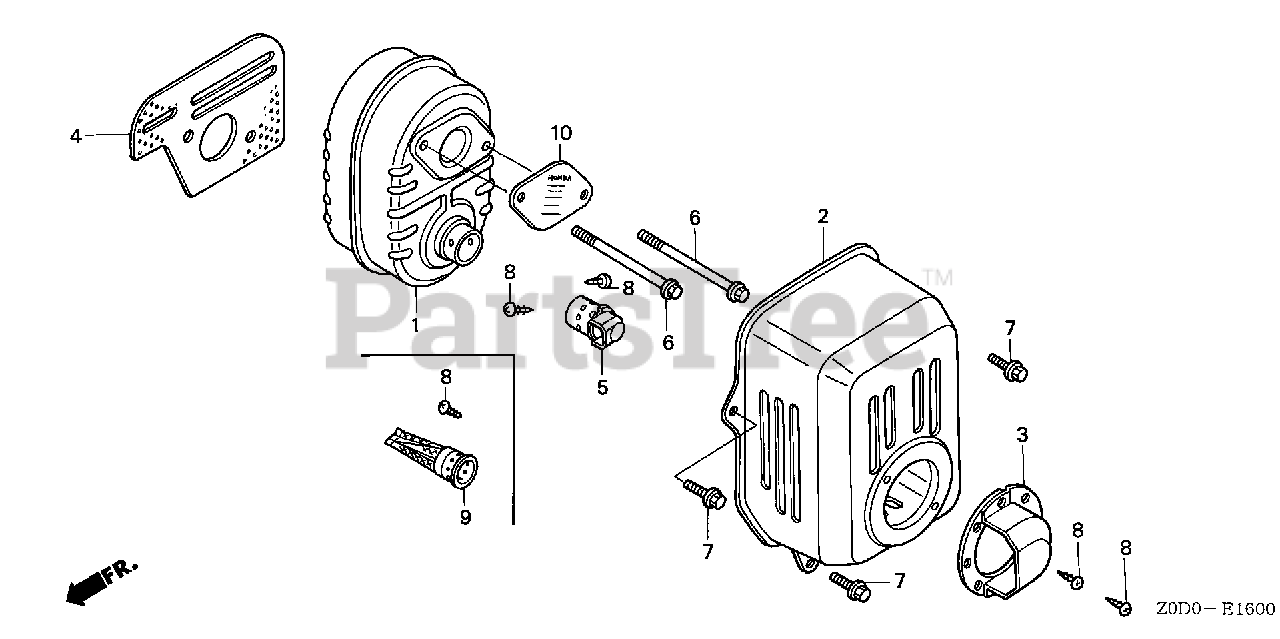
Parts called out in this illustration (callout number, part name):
1	MUFFLER
2	PROTECTOR, MUFFLER
3	CAP, MUFFLER
4	GASKET, MUFFLER
5	DEFLECTOR, MUFFLER
6	BOLT, FLANGE (6X79) (CT200)
7	BOLT, FLANGE (6X14)
8	SCREW, TAPPING (4X6)
9	ARRESTER, SPARK
10	PLATE, ARRESTER NUMBER
